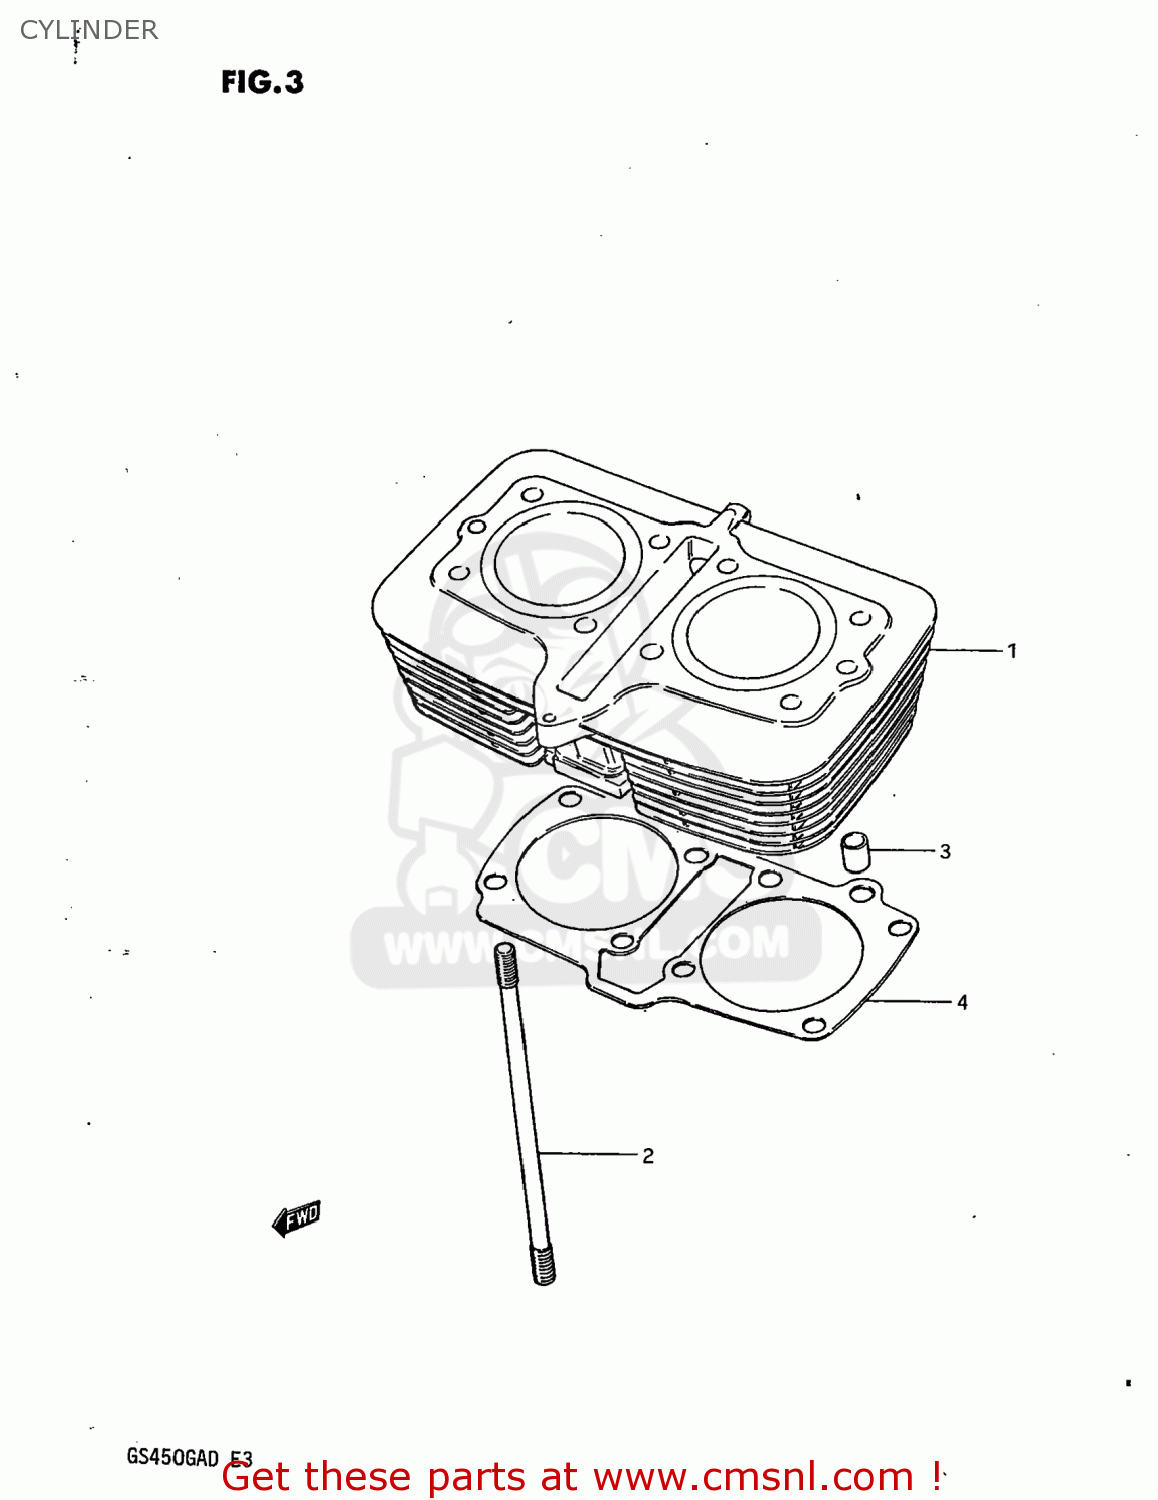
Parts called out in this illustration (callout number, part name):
1	CYLINDER
2	STUD
3	PIN
4	GASKET,CYLINDER (MCA)
